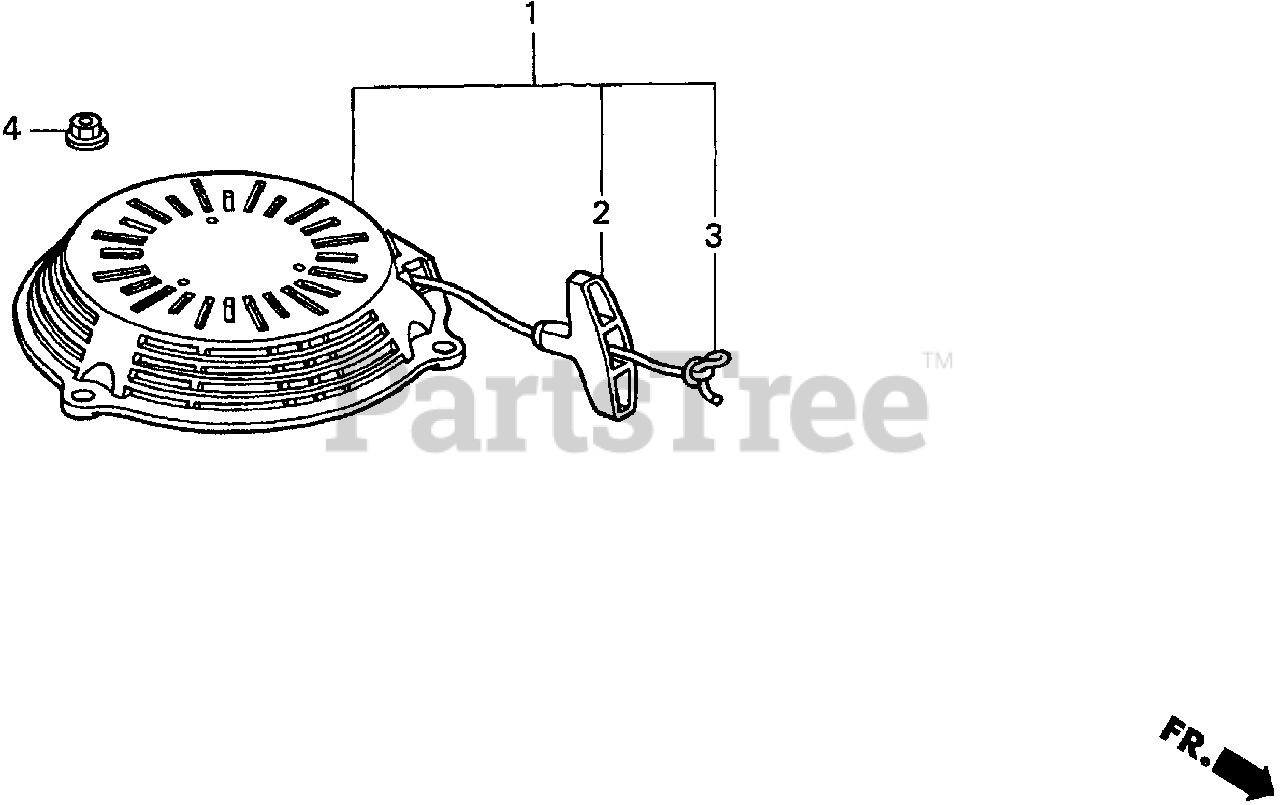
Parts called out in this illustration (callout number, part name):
1	STARTER ASSY., RECOIL *NH1* (BLACK)
2	KNOB, RECOIL STARTER
3	ROPE, RECOIL STARTER
4	NUT, FLANGE (6MM)
